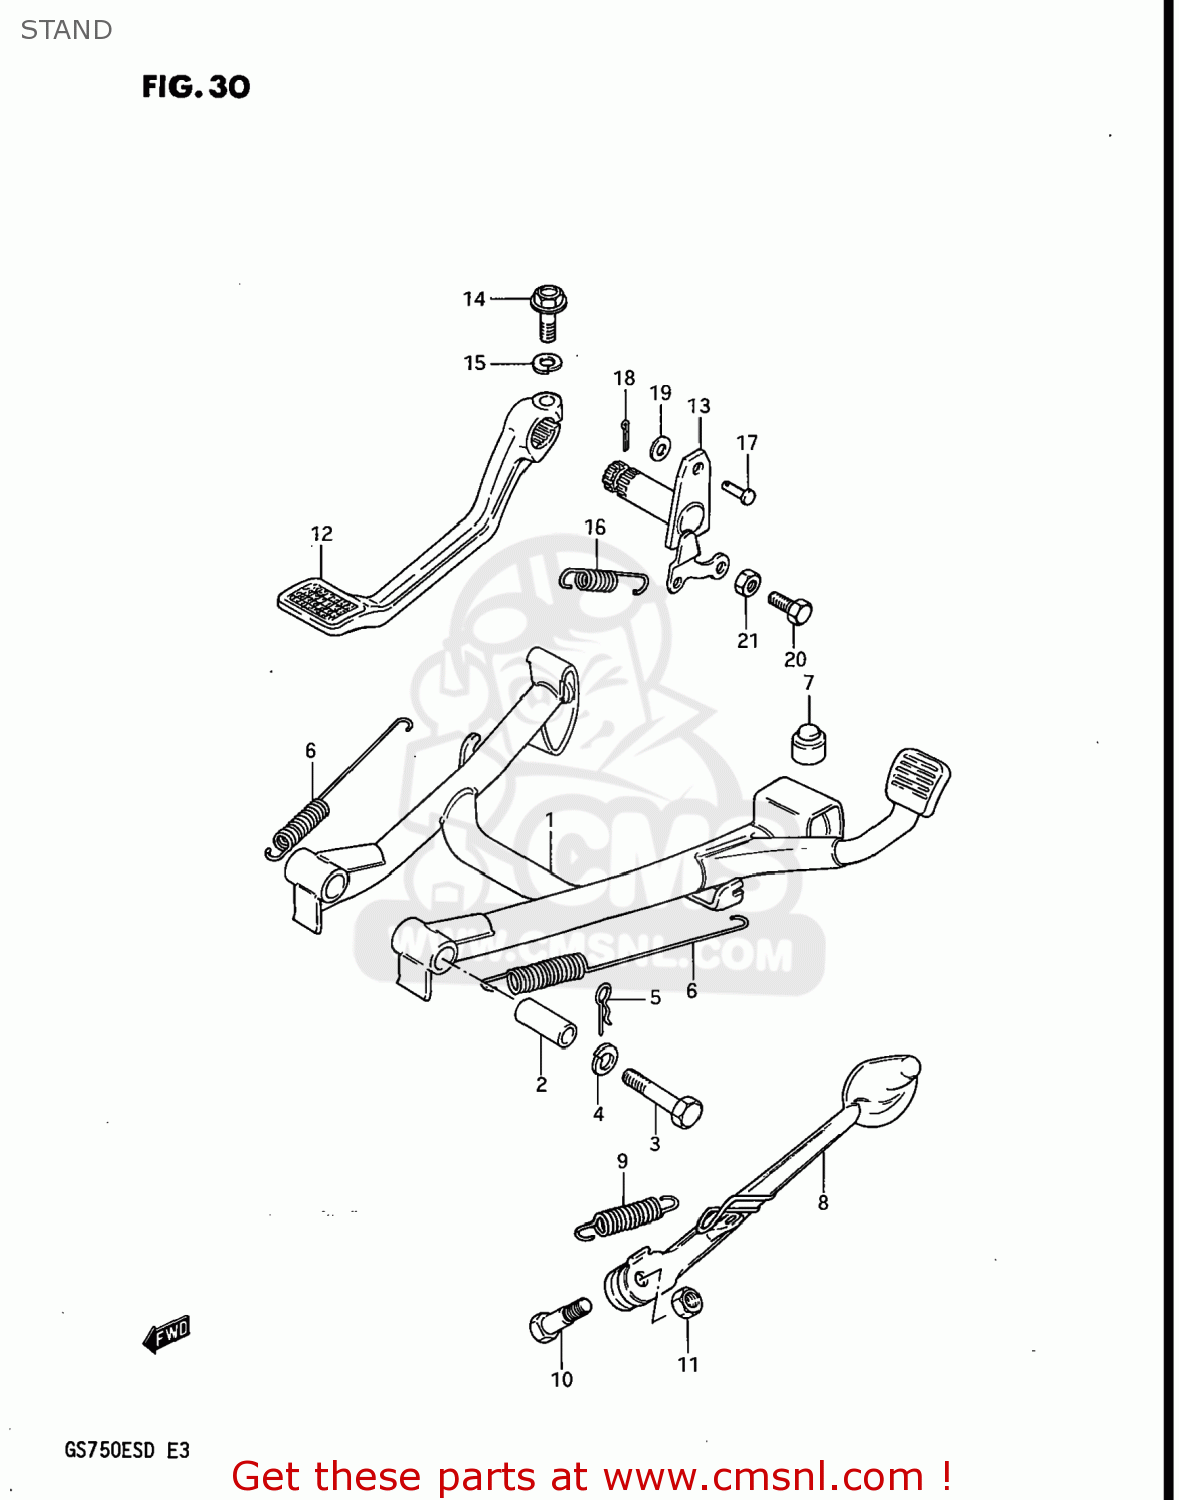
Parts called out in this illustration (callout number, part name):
1	STAND,CENTER
2	SPACER(10X16X38.8)
3	BOLT
4	LOCK WASHER
5	CLIP
6	SPRING
7	CUSHION
8	STAND,SIDE
9	SPRING
10	BOLT(10X32)
11	NUT
12	PEDAL,BRAKE
13	ARM,BRAKE PEDAL
14	BOLT
15	LOCK WASHER
16	SPRING
17	PIN
18	PIN
19	WASHER
20	BOLT
21	NUT
